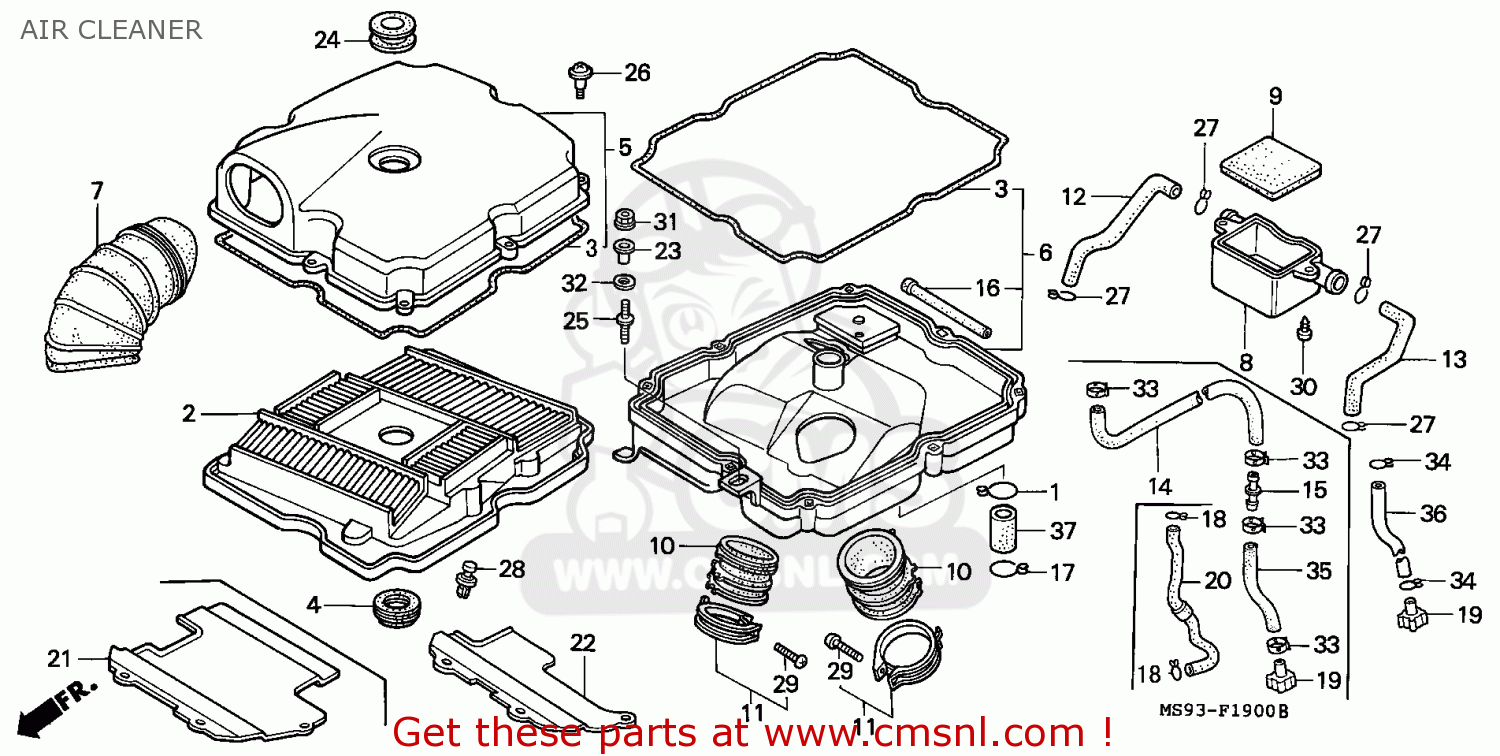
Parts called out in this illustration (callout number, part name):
1	CLIP,DRAIN TUBE
2	ELEMENT COMP,AIR/
3	SEAL AIR/C COVER
4	SEAL,AIR CLEANER
5	COVER,AIR/C CASE
6	CASE COMP.,AIR/C
7	DUCT,AIR CLEANER
8	COVER,SUB AIR CLE
9	FILTER,SUB AIR CL
10	TUBE,AIR/C.CONN
11	BAND A,CONNECTING
12	TUBE,SUB AIR CLEA
13	TUBE,SUB AIR CLEA
14	TUBE,BREATHER
15	JOINT,TUBE
16	TUBE B,BREATHER
17	CLIP B,TUBE
19	PLUG,BRTHR TUBE
21	PLATE,CARBURETOR
23	COLLAR A,TAIL
24	RUBBER,NO BRKT MT
25	BOLT,SPECIAL,6MM
26	SCREW,PAN,5X19
27	CLIP B16,TUBE
28	CLIP, SPLASH SHIELD
29	SCREW,PAN,4X25
30	SCREW TAPP 5X16
31	NUT,FLANGE,5MM
32	WASHER,PLAIN,5MM
33	CLAMP D 12.0 TUBE
35	TUBE,V,8X12X70
37	TUBE,14X55
